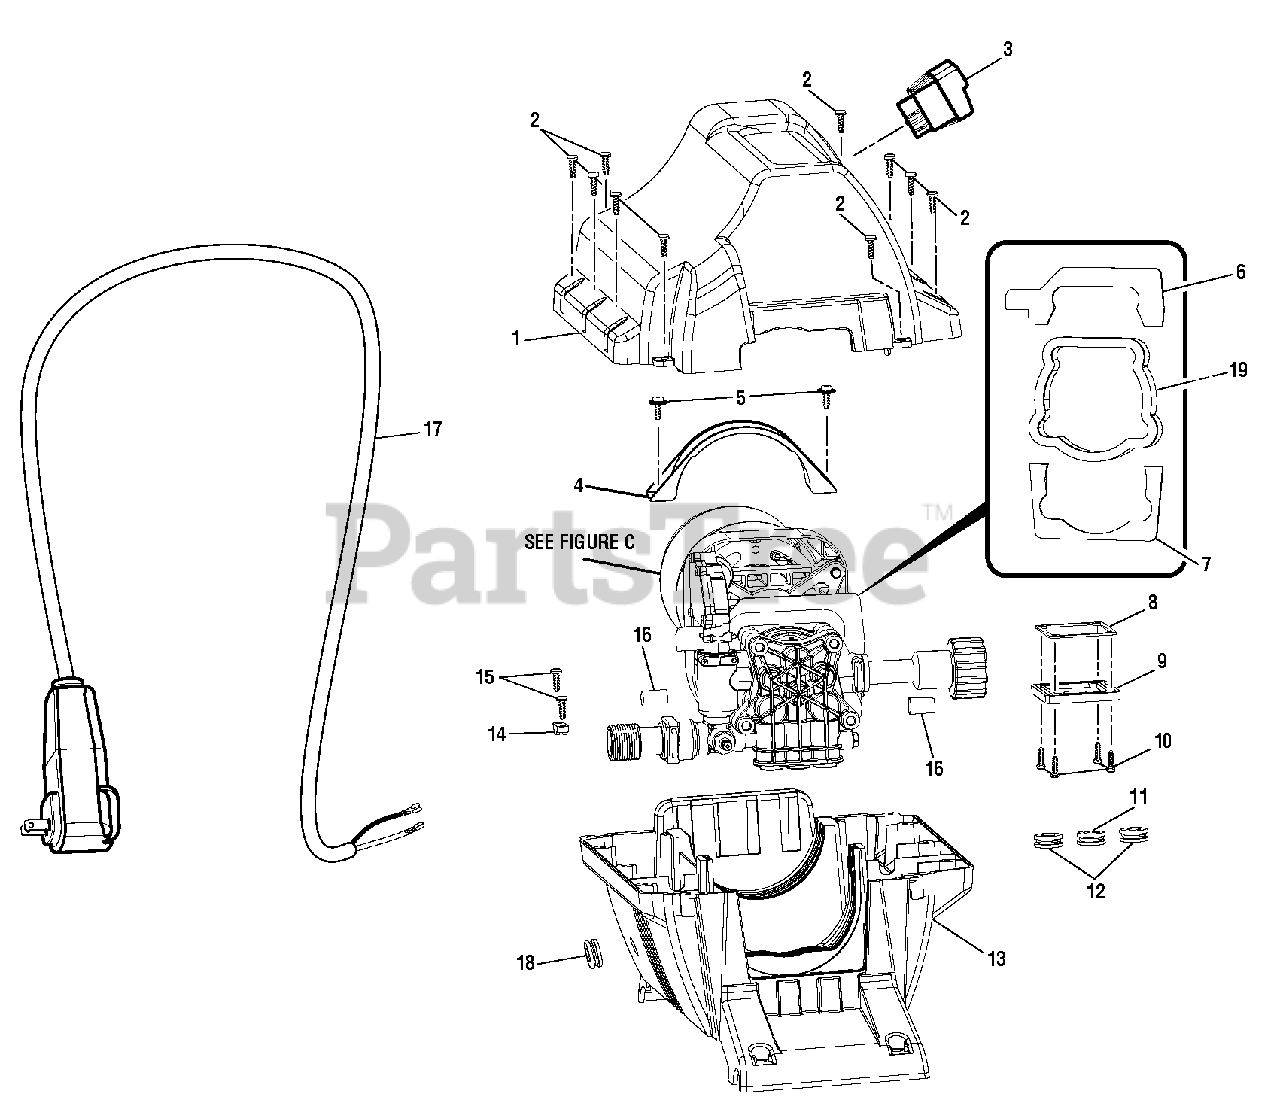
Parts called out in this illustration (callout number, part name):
1	Top Motor Housing
2	Screw (M4 x 15 mm)
4	Motor Bracket
5	Screw (M4 x 12 mm)
6	Upper Gasket
7	Lower Gasket
8	Switch Cover Gasket
9	Switch Cover
10	Screw (M3 x 14 mm)
13	Lower Motor Housing
14	Cord Clamp
15	Screw (M3.5 x 20 mm)
17	Power Cord
